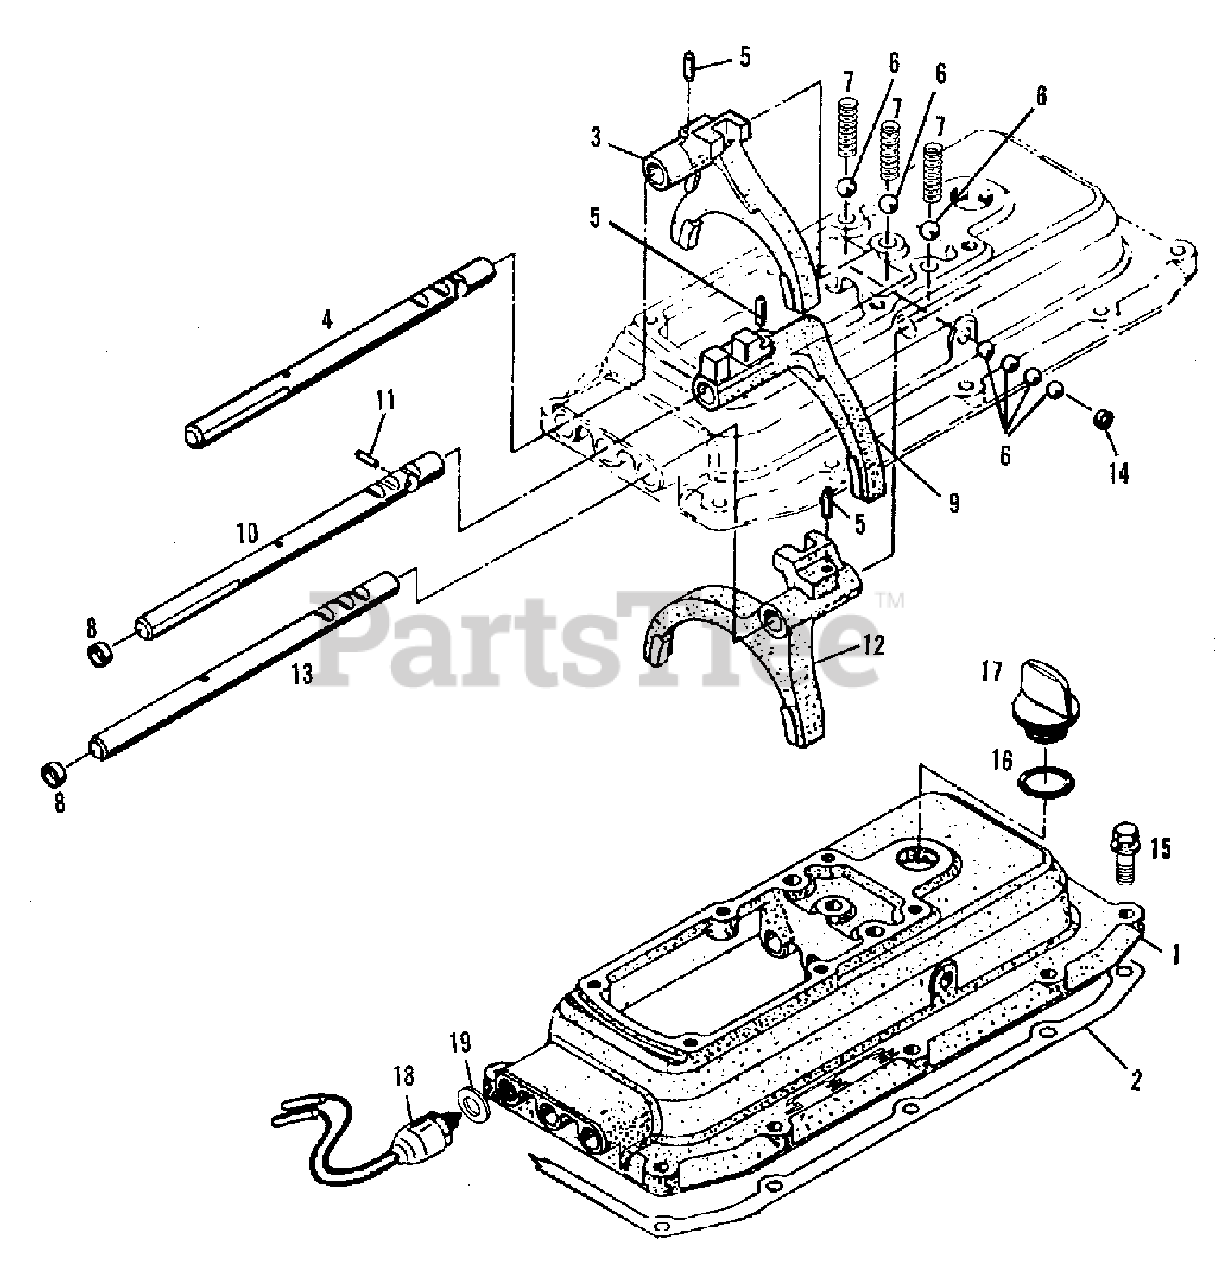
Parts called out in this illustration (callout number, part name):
1	COVER, shift
2	GASKET, shift cover
3	FORK, reverse
4	ROD, reverse
5	PIN, M5 x 18 lock
7	SPRING, detent
8	PLUG, M14
9	FORK, 1st - 2nd
10	ROD, 1st-2nd
11	PIN, interlock
12	FORK, 3rd-4th
13	ROD, 3rd-4th
14	PLUG, M10.5
15	CAPSCREW, M8 x 25. w/lockwasher (Seal lock No.10)
17	PLUG, oil
18	SWITCH ASSEMBLY, safety, start-transmission
